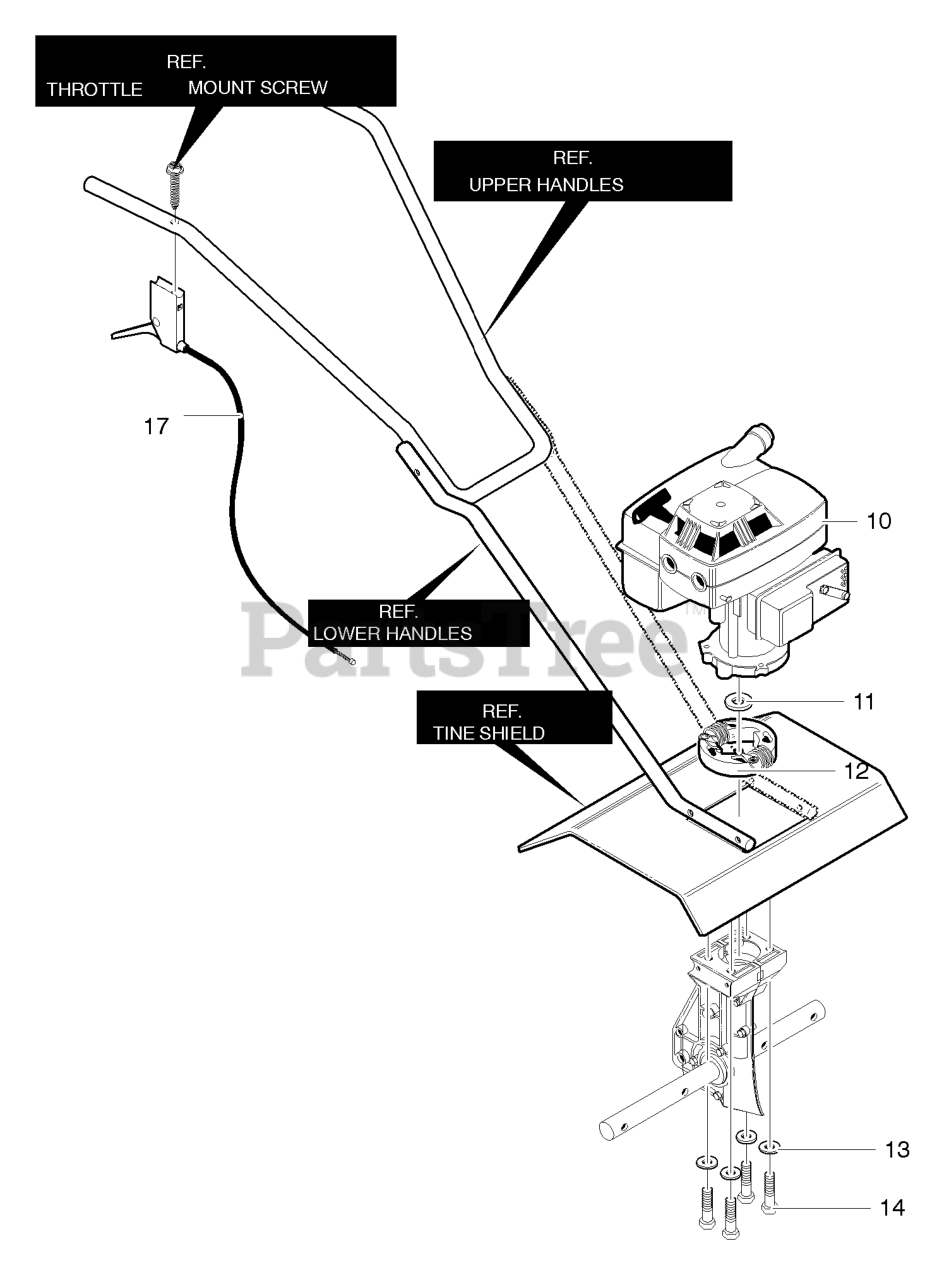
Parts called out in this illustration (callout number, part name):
10	2.0HP Engine
11	Flat washer
13	Washer, Reg
14	Screw
17	Cable, Throttle
